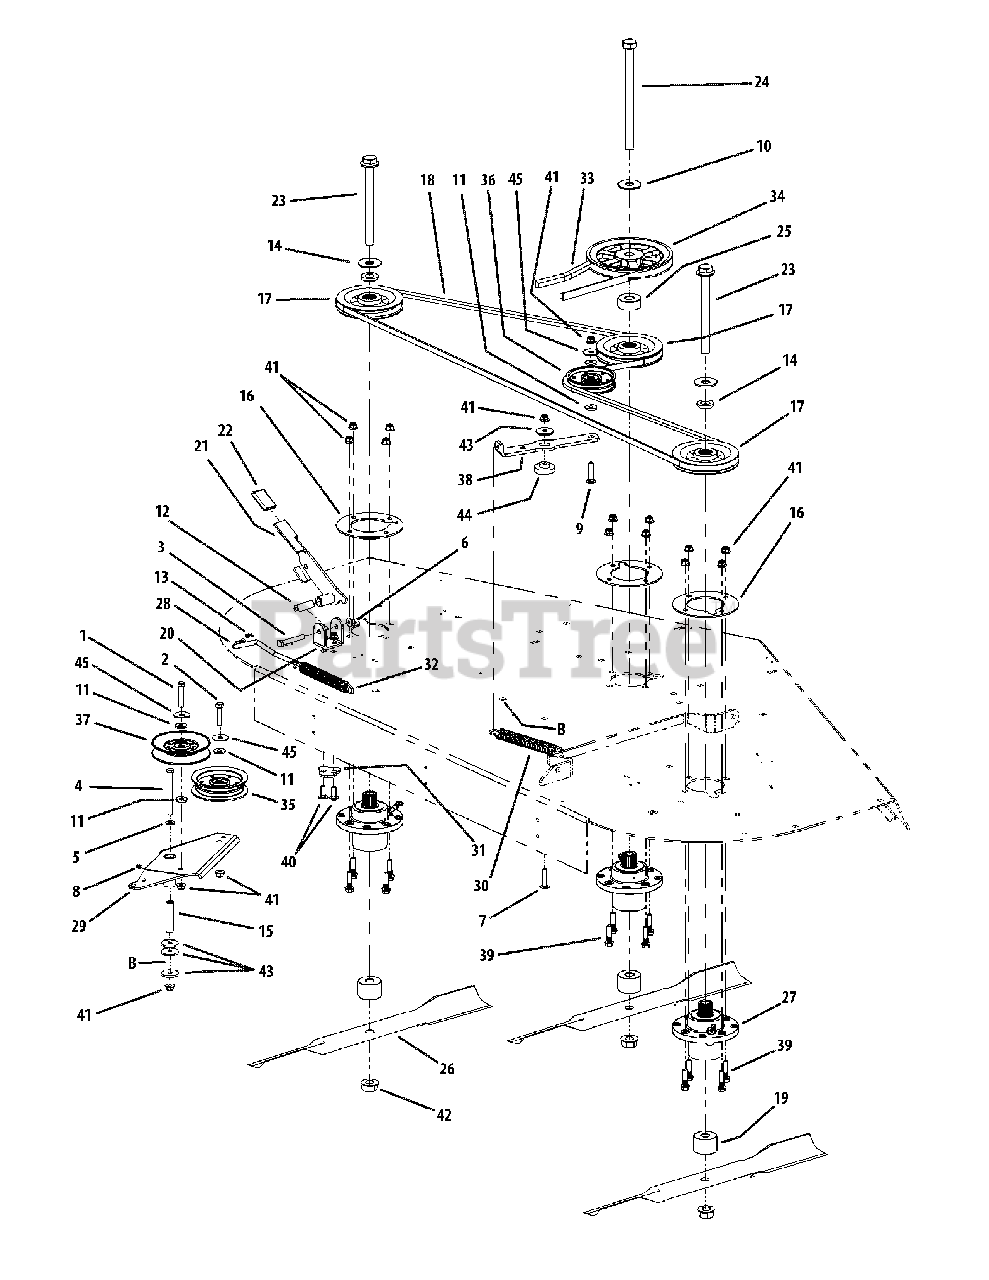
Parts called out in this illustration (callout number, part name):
1	Hex Cap Screw, 3/8-16 x 2.00
2	Hex Cap Screw, 3/8-16 x 1-3/4
3	Hex Cap Screw, #/8-16 x 2-1/2
4	Hex Cap Screw, 3/8-16 x 4.00
5	Washer, 3/8
6	Flange Lock Hex Nut, 3/8-16
7	Carriage Bolt, 3/81-6 x 1-1/2
8	Grease Fitting, 1/4-28 x 3/16
9	Carriage Bolt, 3/8-16, 2.00
10	Flat Washer, .781 ID 2.00 OD, .105
11	Flat Washer, .406 ID, 1.0 OD, .105
12	Spacer, .39 ID x .63 OD x 1.75
13	Cotter Pin, .072 x 1.12 Long
14	Spacer .812 ID x .268 LG
15	Spacer, .39 ID x .625 OD x 2.75
16	Aluminum Spindle Support Plate
17	V-Pulley, 5.75 OD
18	V-Belt, B Section x 124.0 Lg
19	Spacer, .760 ID x 2.00 OD x 1.28
20	Tension Idler U-Bracket
21	Handle Tension Weldment
22	Tension Idler Handle Grip
23	Hex Cap Screw, 3/4-16, 7.50
24	Hex Cap Screw, 3/4-16, 9.50
25	Spacer, .76 ID x 2.0 OD x .790
26	Bahia Blade, 25.0, .756 ID
27	Aluminum Spindle Assembly
28	Spring Tension Rod
29	Idler Arm Assembly
29	Bearing Sleeve
30	Extension Spring, .94 x OD x 7.57
31	Adaptor Plate
32	Extension Spring, .94 OD x 7.72 Lg
33	V-Belt, B Section x 107.0
34	V-Pulley, 7.450 OD x .750 Bore, Cast
35	Idler Pulley, 4.06 OD
36	Idler Pulley, 4.06 Dia.
37	Idler Pulley, 5.06 Dia.
39	Bolt, 3/8-16 x 1.5
40	Carriage Bolt, 3/8-16 x 1
41	Nut, 3/8-16, Nylon Flange Lock
42	Flange Hex Nut, 3/4-16
43	Washer, .390 x 1.500 x .134
44	Shoulder Spacer, .854 x .280
45	Washer, .406 x 1.92 x .060
